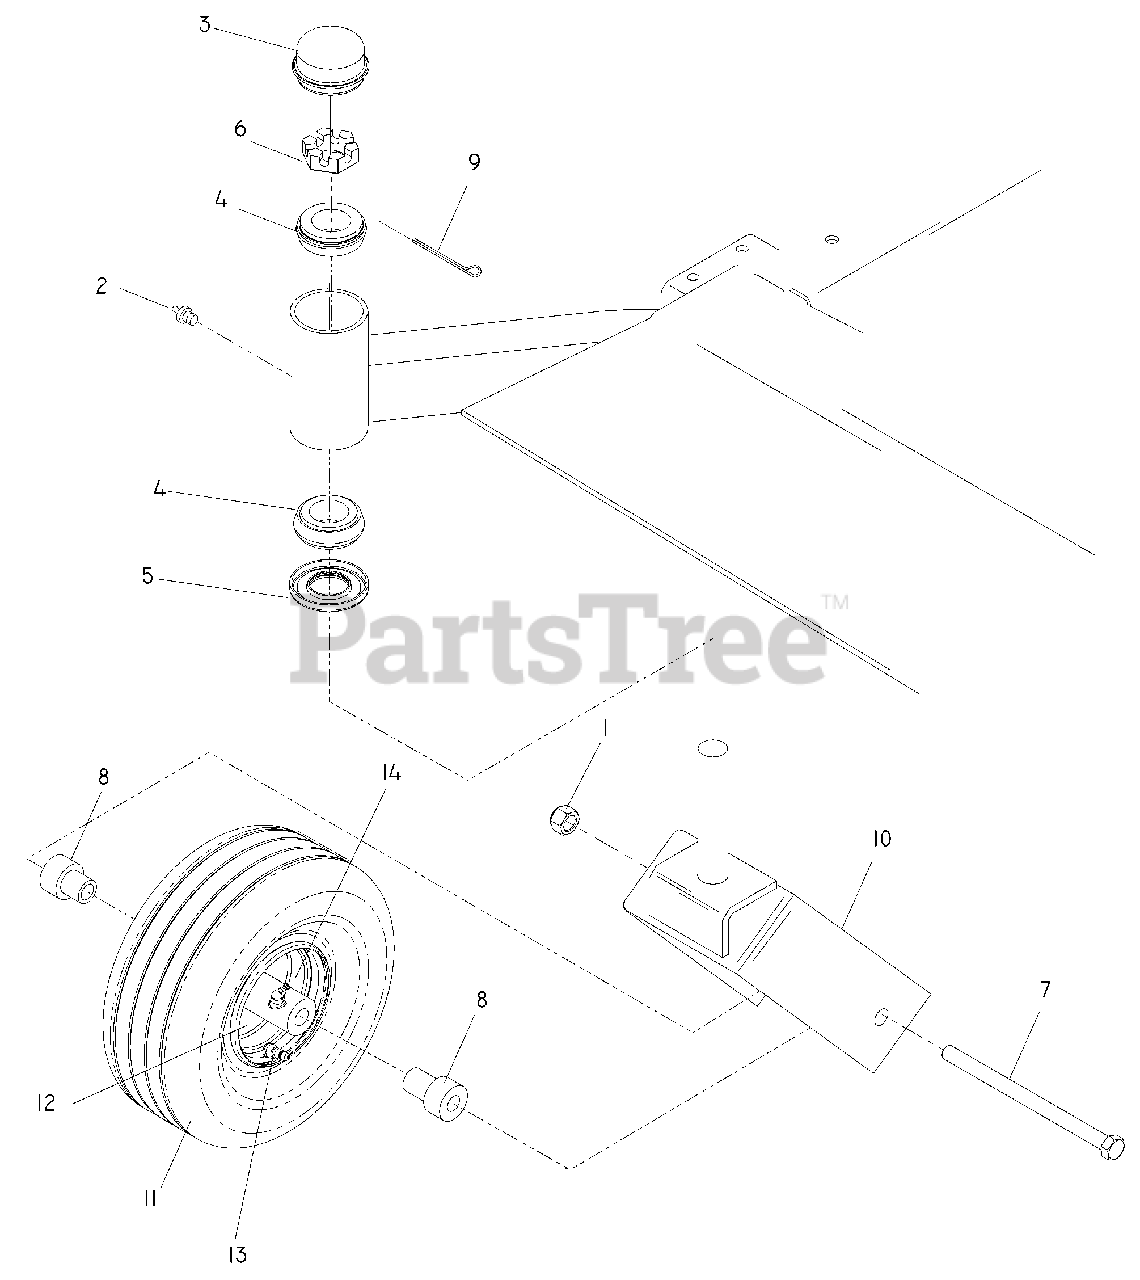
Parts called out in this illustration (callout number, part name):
1	NUT ½ -13, NYLOC
3	CAP GREASE
4	BEARING, TAPERED
6	NUT 1-14, SLOTTED JAM
7	HCS, ½-13 x 9½
9	PIN COTTER, 1/8 x 2
10	CASTER YOKE
11	TIRE, COMPLETE
13	VALVE STEM
14	ZERK
